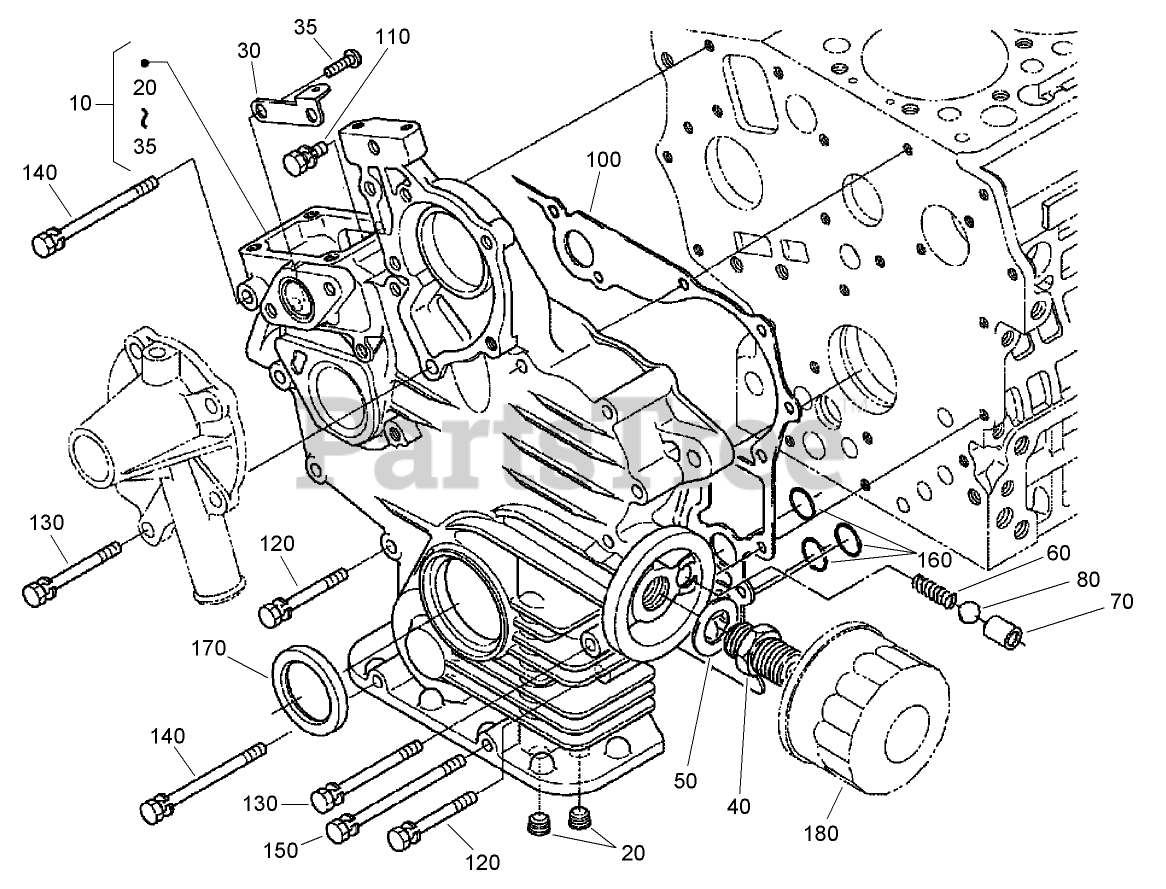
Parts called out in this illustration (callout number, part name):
10	CASE-GEAR
30	STAY-SPRING, START
40	JOINT-PIPE
50	WASHER-PLAIN
60	SPRING
70	SEAT-VALVE
100	GASKET-GEARCASE
120	BOLT
160	O-RING
170	SEAL-OIL
180	CARTRIDGE-FILTER, OIL
